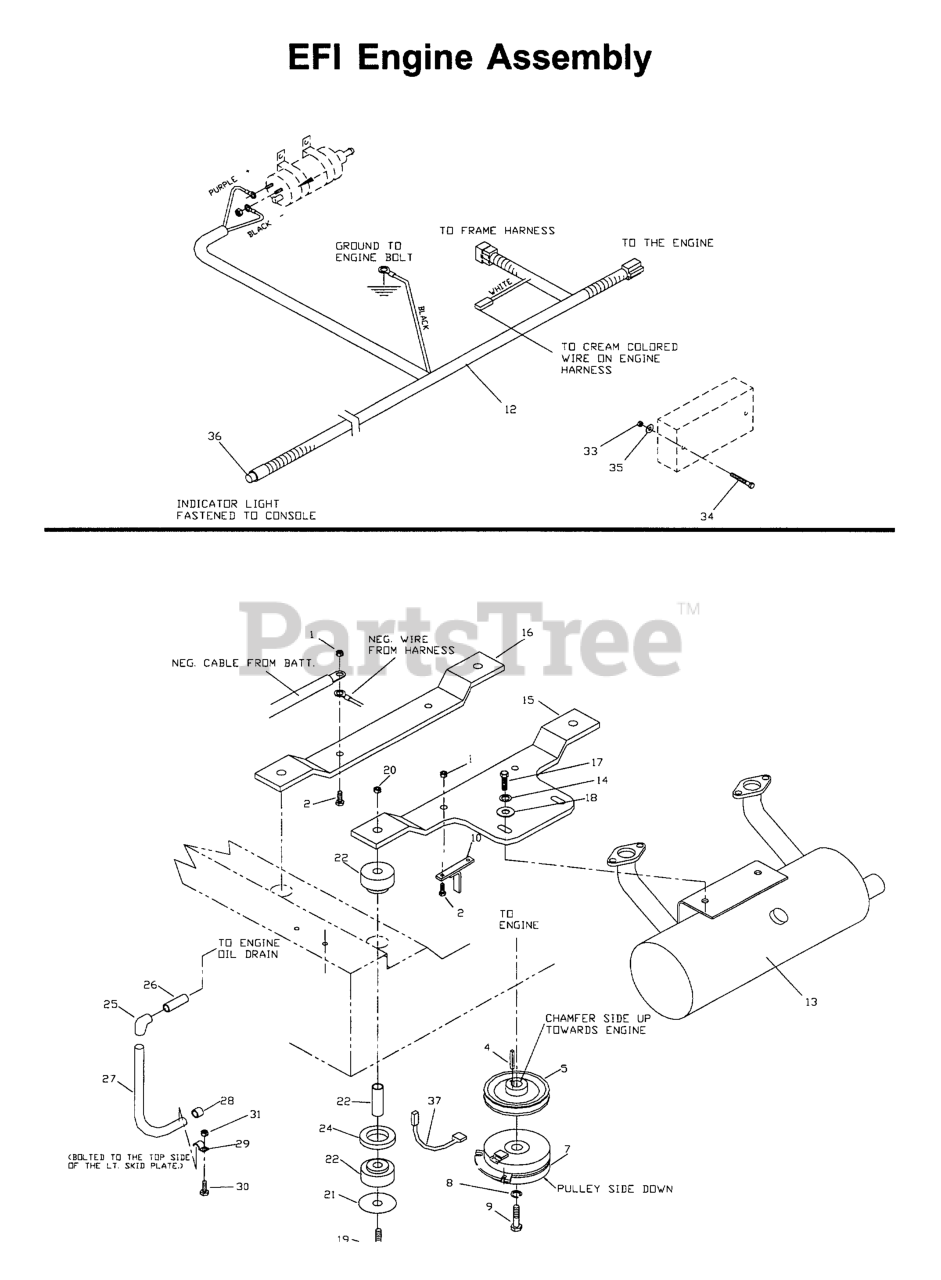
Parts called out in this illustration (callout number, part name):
1	NUT 5/16C CENTERLOCK
2	HCS 5/16C X 1 3/4
4	KEY 1/4" SQ X 1 7/8"
7	ELECTRIC CLUTCH W/CABLE
8	WASHER 7/16 LOCK
9	BOLT 7/16F X 2 1/2
10	CLUTCH TIE DOWN
12	WIRE HARNESS - EFI
13	MUFFLER EFI KOHLER GEN II
14	WASHER.LOCK.HVY.HLCL.SPR.5/16
15	REAR ENGINE MOUNT
16	ENGINE MOUNT
17	HCS 5/16C X 1
18	WASHER 5/16 FLAT
19	HCS 1/2C X 3 1/4
20	NUT 1/2-13 HEX NYLOC ZD
21	ISOLATOR WASHER
24	ISOLATOR SPACER
25	90 DEG.ELBOW 3/8NPT
26	PIPE 3/8 NPT 1-1/2
27	OIL DRAIN HOSE
30	HCS 1/4C X 3/4 HCS
31	NUT 1/4C CENTER LOCK
32	SCREW #10 X 1/2 SELF TAPPING
33	NUT 10-24 NYLOC
34	BOLT 10-24 X 2
35	WASHER #10
36	INDICATOR CARTRIDGE LAMP
37	CLUTCH HARNESS
